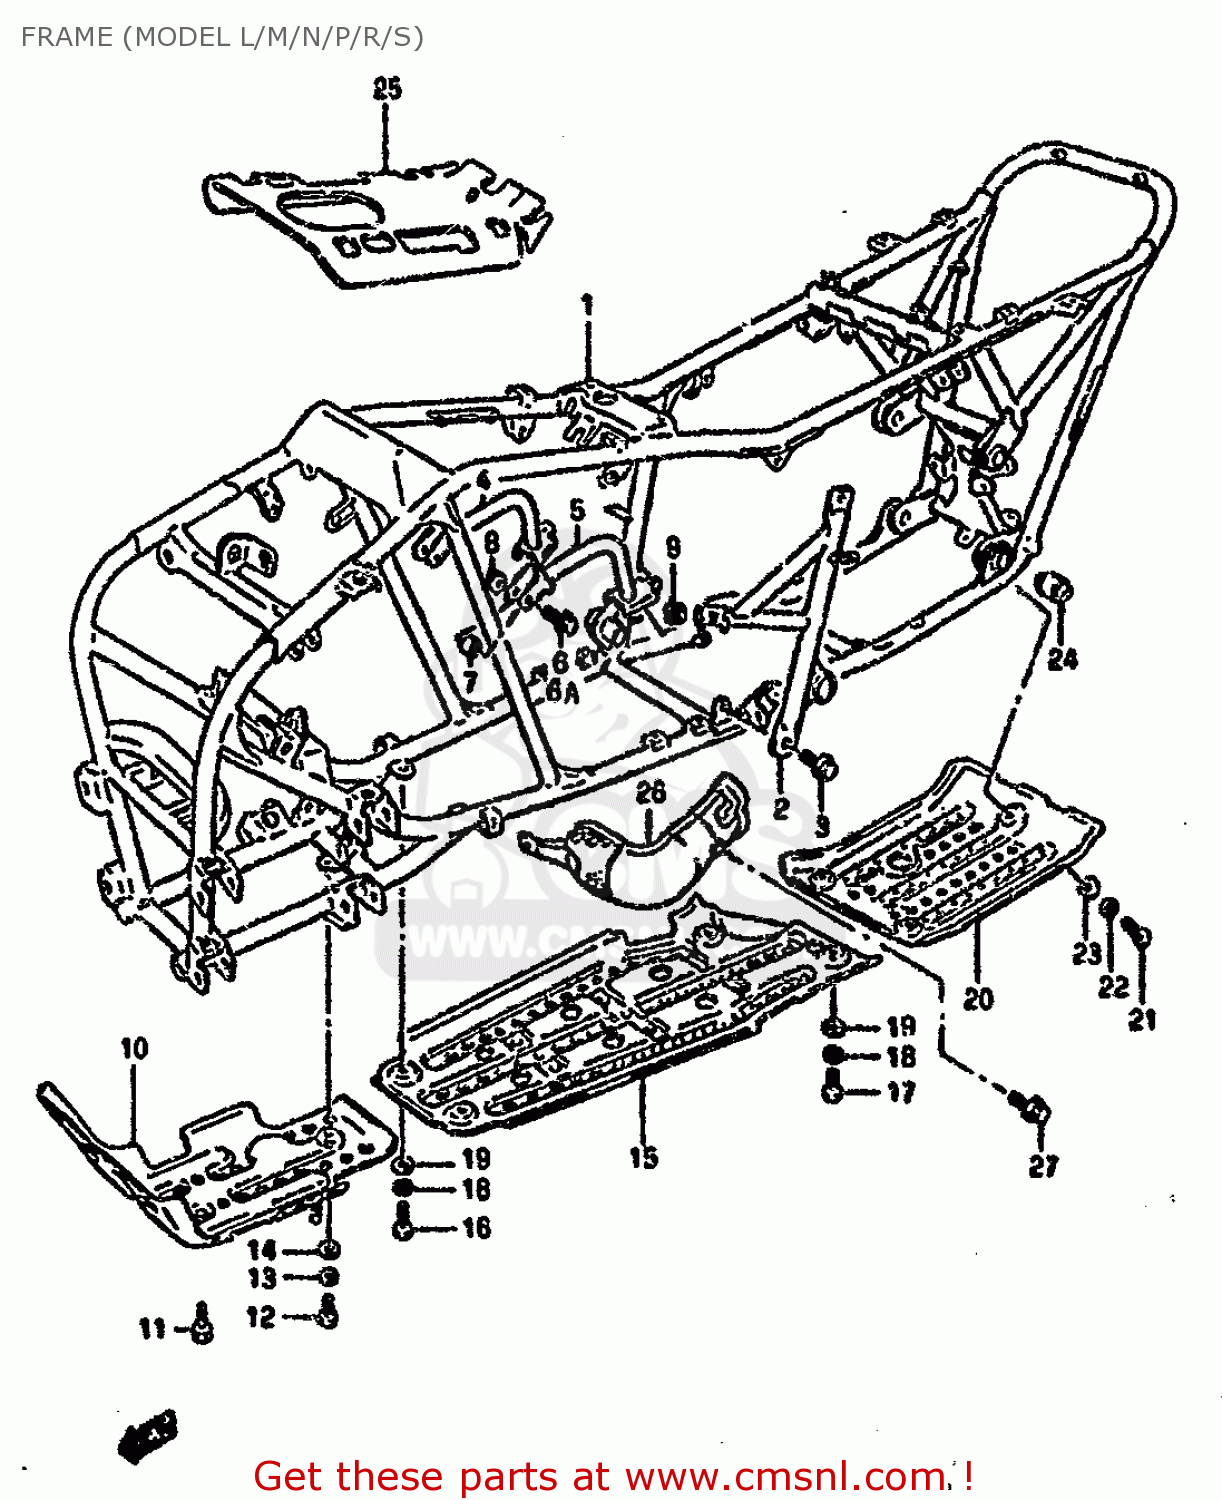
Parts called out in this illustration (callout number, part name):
1	FRAME SET (BLACK)
2	TUBE,ENGINE MOUNT FR
3	BOLT(10X20)
4	TUBE,COOLING FAN,R
5	TUBE,COOLING FAN,L
6	BOLT
6A	WASHER (8.5X24X2.3)
7	SPACER(8.5X12X19)
8	NUT
9	CAP,FR GRIP
10	PROTECTOR,FRONT
11	BOLT
12	BOLT
13	WASHER,LOCK
14	WASHER, LOWER
15	PROTECTOR
16	BOLT, REAR
17	BOLT
18	LOCK WASHER
19	WASHER
20	PROTECTOR COMP,ENGINE
21	BOLT
22	WASHER,LOCK
23	WASHER, LOWER
24	BUSH
25	MUD GUARD
26	COVER,MUD
27	BOLT
